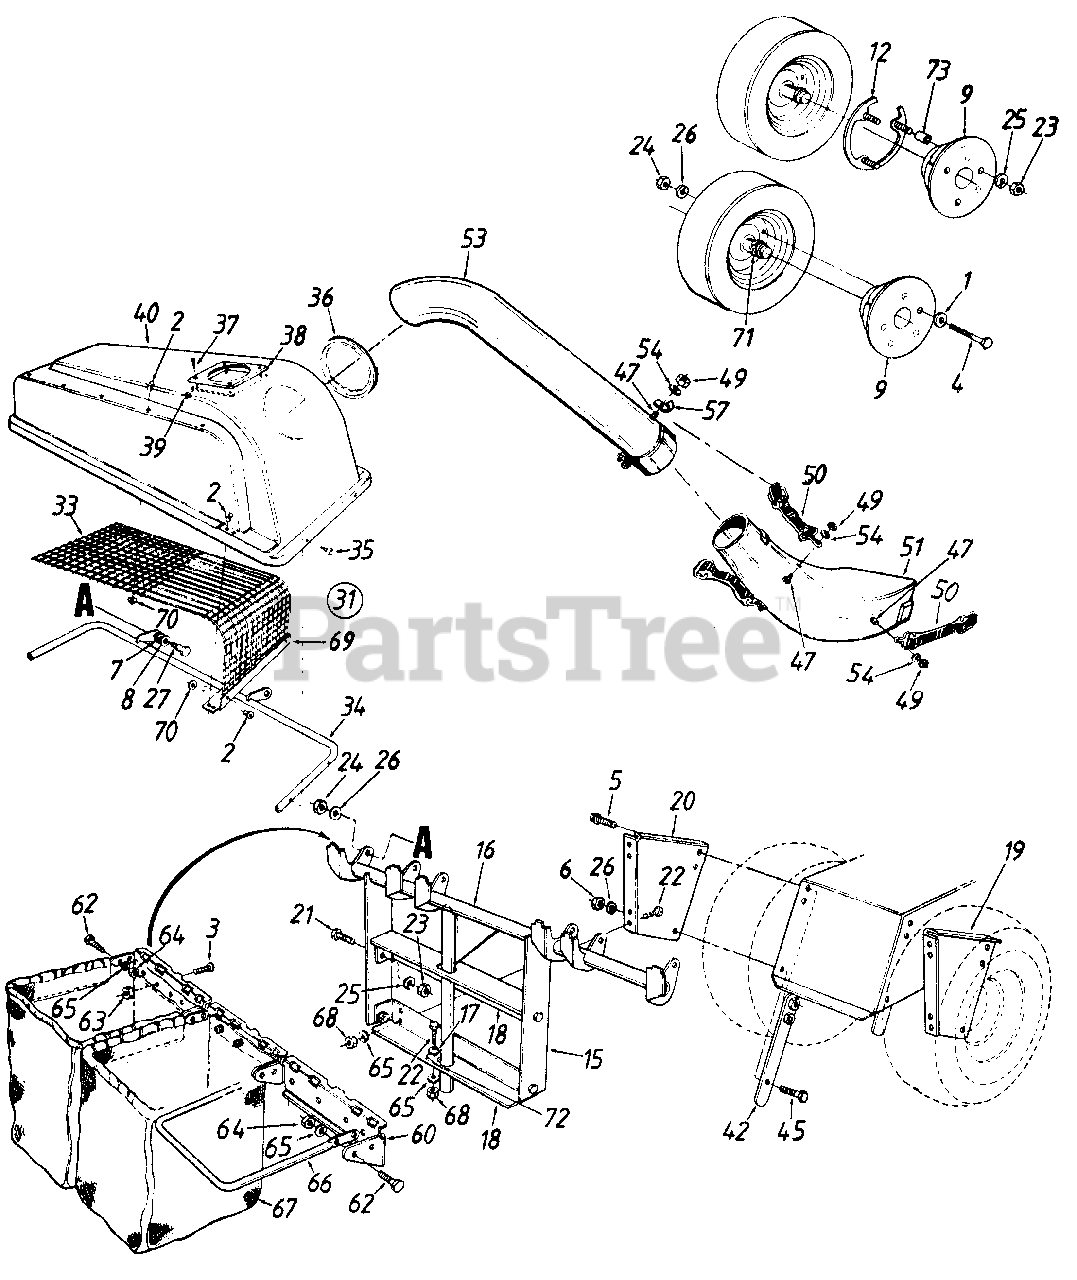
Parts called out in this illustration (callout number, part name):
1	Fl-Wash. .385" I.D.
2	Pop Rivet
3	Truss Mach. Scr. #10-24 x .38" Lg.
4	Hex Bolt 3/8-16 x 4.5" Lg.
5	Hex Wash. Hd. Tap Scr. 5/16-18 x .62"
6	Hex Nut 3/8-24 Thd.
7	Bell-Wash. .515" I.D.
8	Fl-Wash. .510" 1 .D.
9	Wheel Weight
12	Wheel Weight Snap Ring
15	Catcher Support Tube Mtg. Brkt.
18	Catcher Latch and Support Brkt.
22	Hex Bolt 1/4-20 X .62" Lg.- 0 Grade 5
23	Hex Nut 5/16-18 Thd.
24	Hex Nut 3/8-16 Thd.t
25	L-Wash. 5/16" I.D.
26	L-Wash. 3/8" I.D.
27	Shld. Bolt 3/8-16 x .500" Dia.
31	Grass Catcher Cover Ass'y. Comp.
37	Truss Mach. B-Tap Scr. #10 0 x.5" Lg.
38	Plastic Plate
39	Speed Nut
40	Grass Catcher Cover
47	Hex Bolt 1/4-20 x .50" Lg.
49	Hex Ins. L-Nut 1/4-20 Thd.
50	Retainer Strap Ass'y.
51	Discharge Chute
53	Catcher Elbow Tube
54	L-Wash. .270" I.D. x .57" O.D.
57	Retainer Hook Brkt.
62	Hex Bolt 1/4-28 x .75" Lg.
63	Hex Sems Nut #10-24 Thd.
64	Hex Nut 1/4-28 Thd.'
65	L-Wash. 1/4" I.D.
66	Catcher Bag Frame
67	Grass Catcher Bag
68	Hex Nut 1/4-20 Thd.
71	Foam Strip 1-1/8" x 1-1/2" x 3/8"
